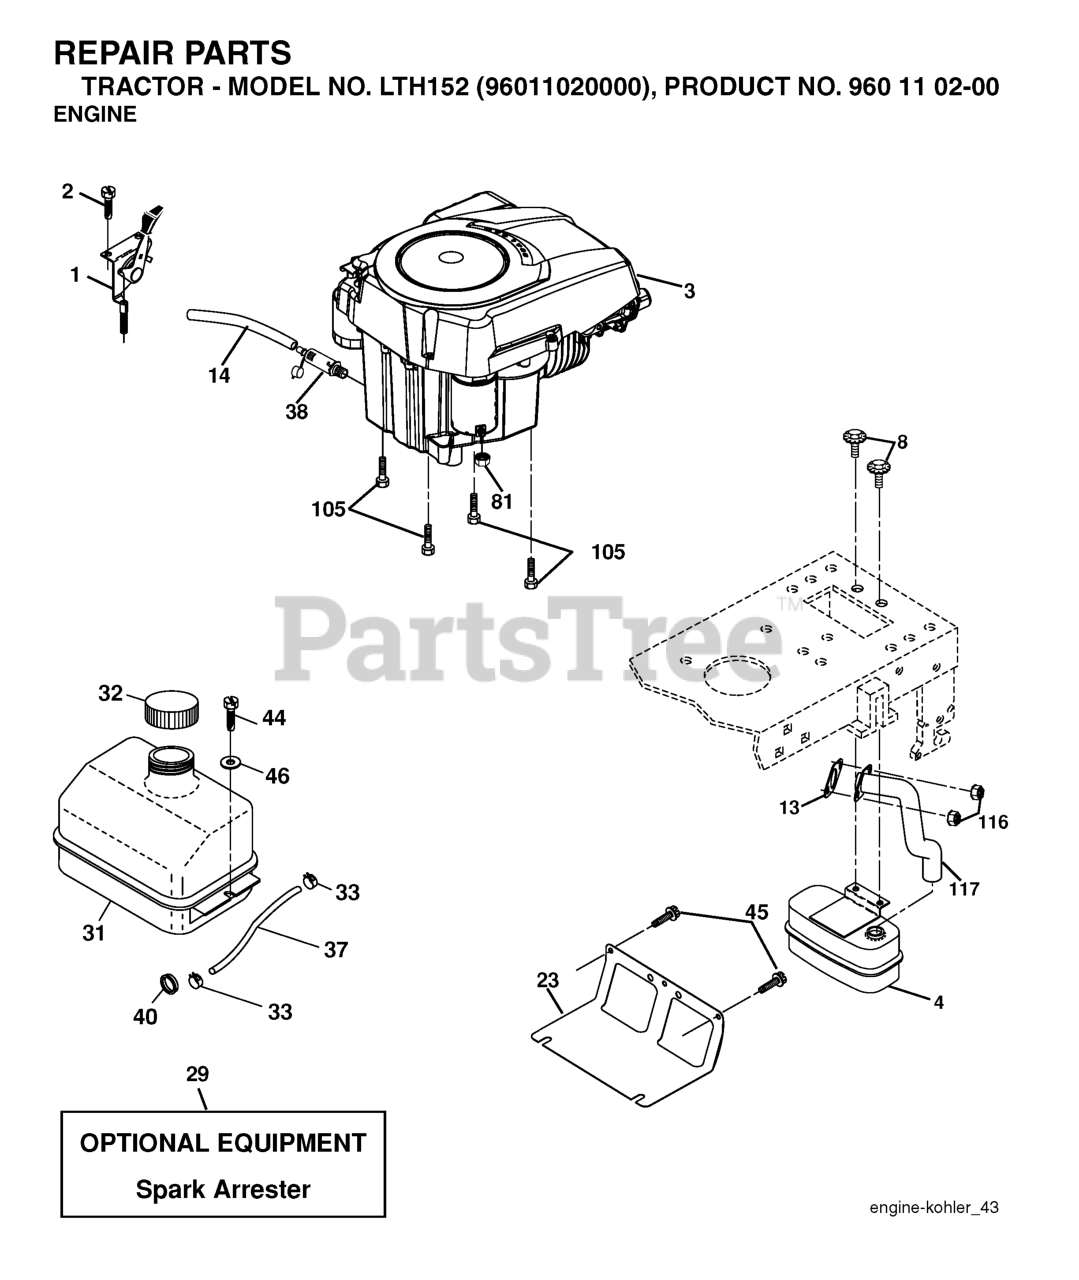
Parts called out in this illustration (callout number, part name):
1	CONTROL.THROTTLE.LT/YT
2	SCREW
4	MUFFLER.SINGLE.CYL.KOHL/B&S
8	BOLT.5/16-18UNCX3/4 W/SEMS.BLK
13	GASKET.EXHAUST.KOHLER
14	TUBE, DRAIN OIL ASM.
23	SHIELD.BROWNING.DBR.GUARD
29	KIT.SPARK ARRESTOR 794945 B&S
31	FUEL TANK
32	FUEL CAP
33	HOSE CLAMP
37	LINE.FUEL.20
38	PLUG DRAIN OIL EASY
44	SCREW HEXWSHR 1/4-20X3/4
45	SCREW, 3/8-16X3/4
81	NUT
105	SCREW 3/8-16X1
116	NUT.HEX.FLANGE.TOPLOCK
117	RP.TUBE.EXHAUST.KOHL.COURAGE
